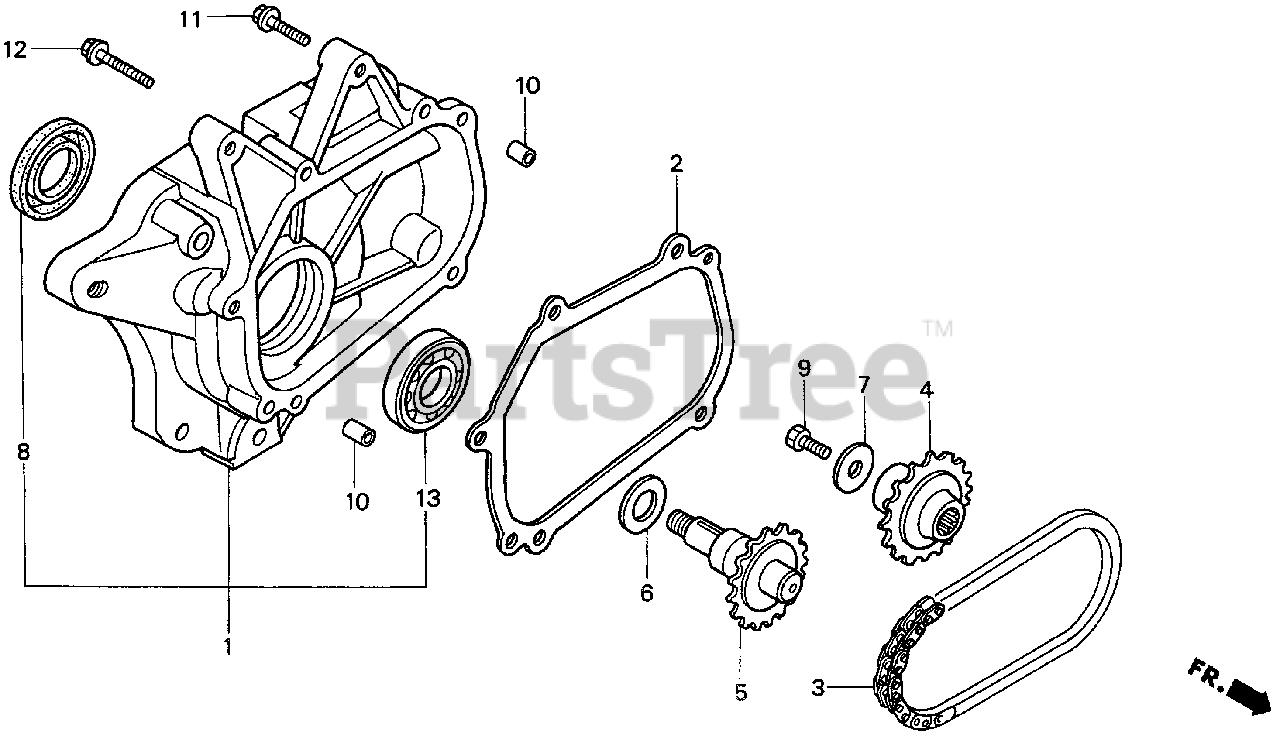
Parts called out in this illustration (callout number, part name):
1	COVER ASSY., CHAIN CASE
2	GASKET, CHAIN CASE COVER
3	CHAIN, P.T.O. DRIVE
4	SPROCKET, DRIVE (17T)
5	SHAFT, P.T.O.
6	SPRING, THRUST
7	WASHER (8MM)
8	OIL SEAL (25X38X7)
8	OIL SEAL (25X38X7) (ARAI)
9	BOLT, HEX. (8X25)
10	PIN C, DOWEL (8X14)
11	BOLT, FLANGE (8X35)
12	BOLT, FLANGE (8X55)
13	BEARING, RADIAL BALL (6005)
